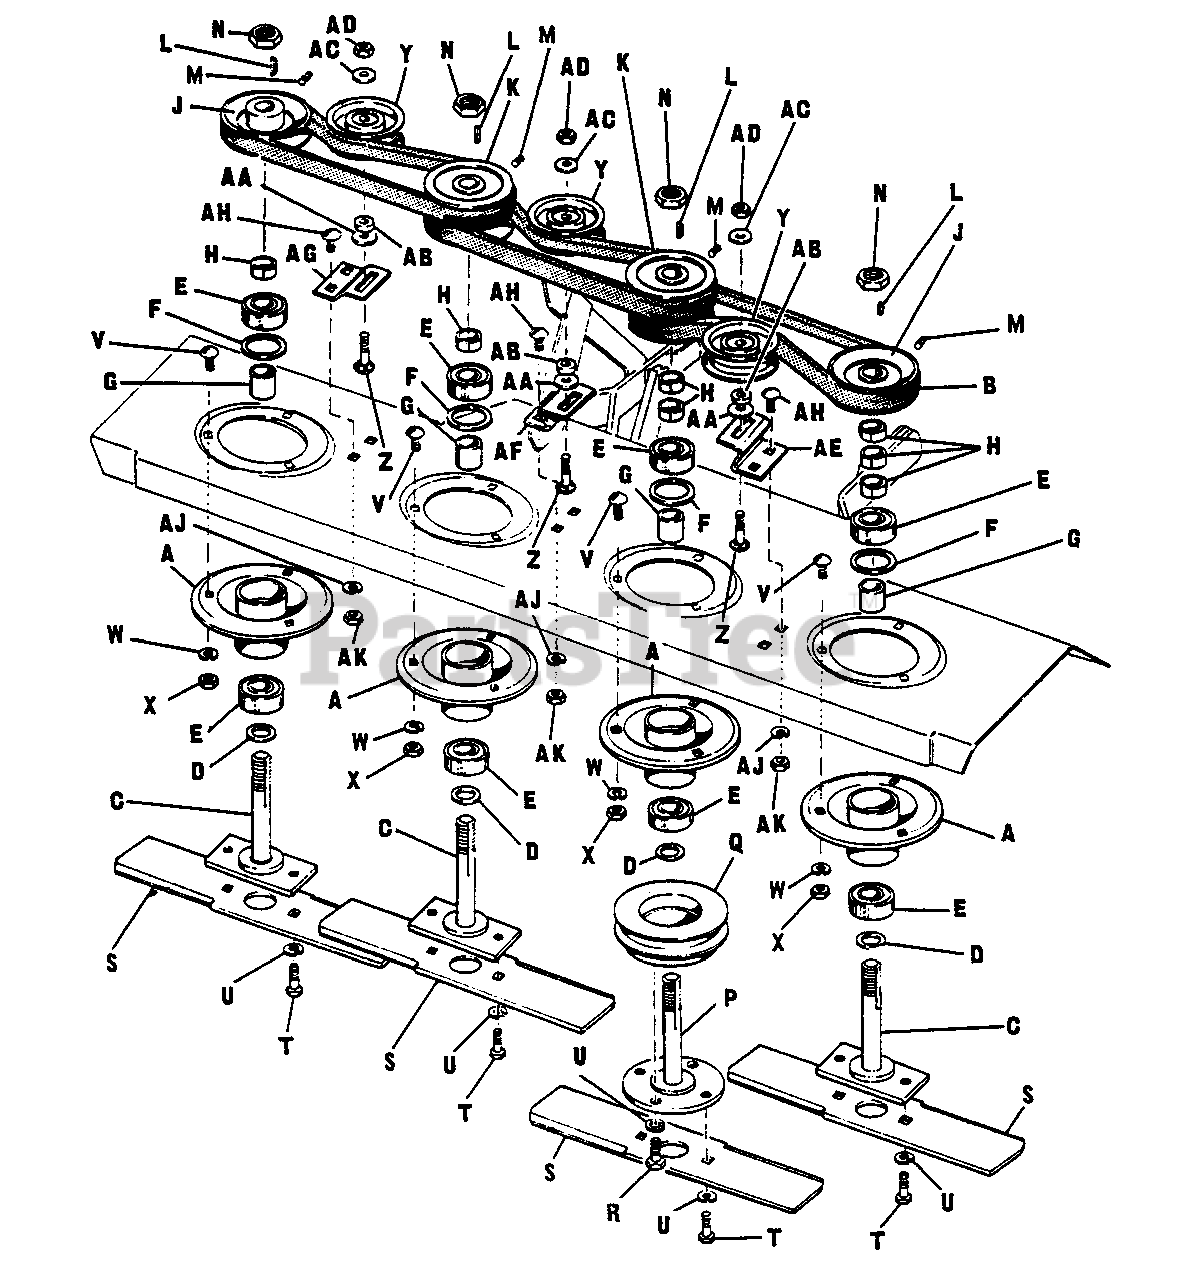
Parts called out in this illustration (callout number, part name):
A	Arbor Tube Assembly
C	Arbor Assembly
K	Double Pulley
M	Set Screw, 5/16"-18 x 3/8"
N	Jam Hex. Nut, 3/4"-16
P	Arbor Assembly
Q	Arbor Drive Pulley
R	Hex Cap Screw, 3/8"-16 x 7/8"
S	Knife Blade
T	Hex. Cap Screw, 3/8"-16 x 5/8"
U	Lock Washer, 3/8"
V	Carriage Bolt, 3/8"-16 x 3/4"
W	Lock Washer, 3/8"
X	Full Hex. Nut, 3/8"-16
Y	Idler Pulley
Z	Carriage Bolt, 3/8"-16 x 1-1/2"
AA	Plain Washer, 3/8"
AC	Plain Washer, 5/16"
AD	Full Lock Hex. Nut, 3/8"-16
AE	Idler Support, L.H.
AF	Idler Support
AG	Idler Support, R.H.
AH	Carriage Bolt, 5/16"-18 x 3/4"
AJ	Lock Washer, 5/16"
AK	Full Hex. Nut, 5/16"-18
